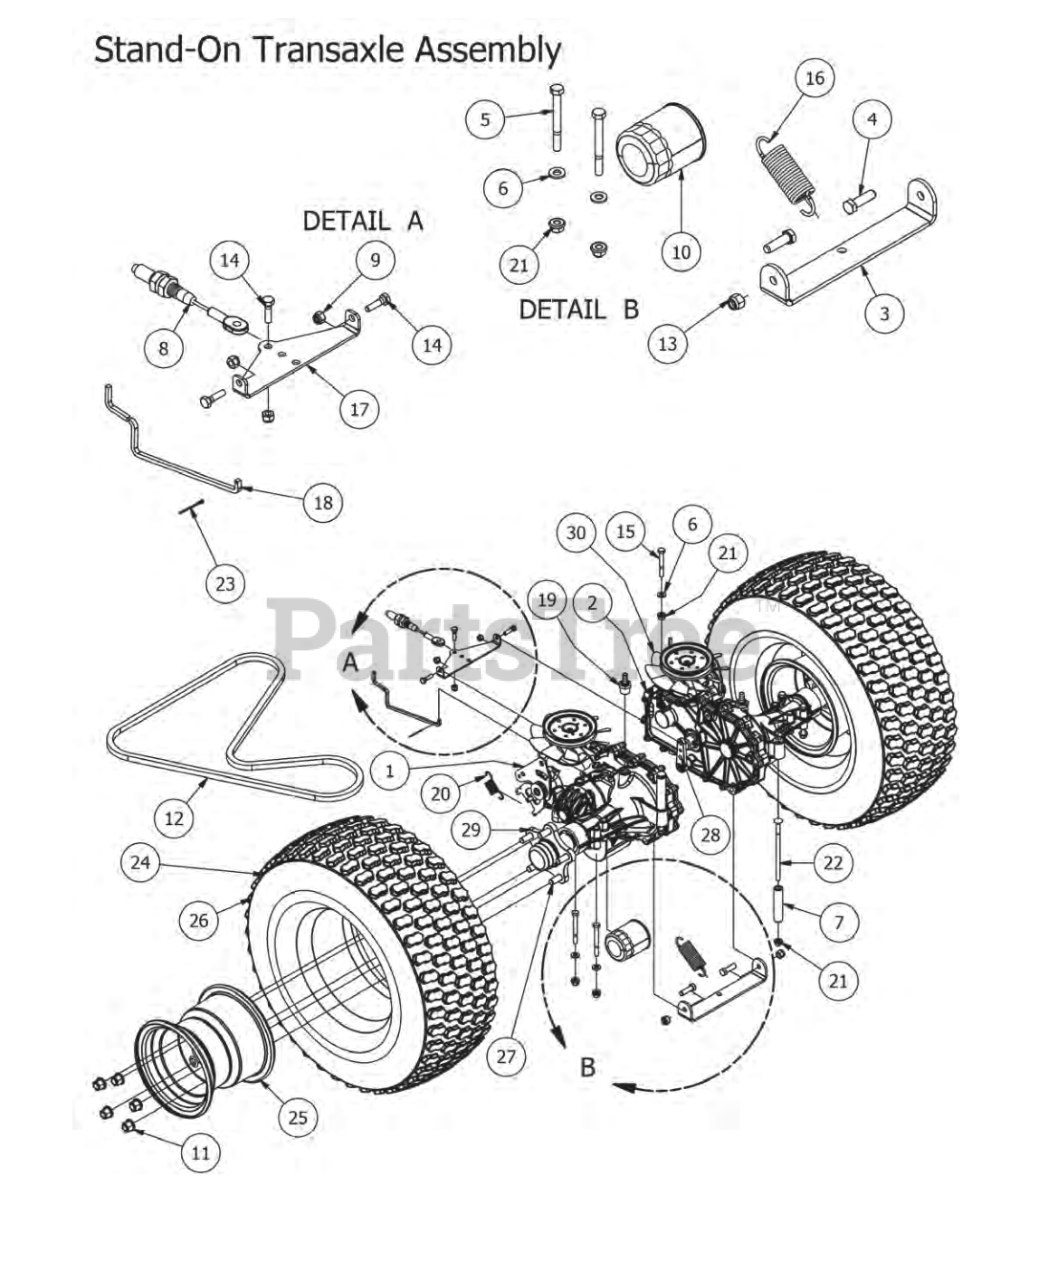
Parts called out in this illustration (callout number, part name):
1	Left 3400 IZT
2	Right 3400 IZT
3	Crossover Bar for ZT
4	3/8" x2" Hex Bolt
5	5/16" x 3" Hex Bolt
6	5/16" Flat Washer
7	3 1/4" Spacer
8	Brake Cable
9	1/4" Nylock Nut
10	Transaxle Hydro Filter
11	Acorn Lug Nut
13	3/8 Nylock Nut
14	1/4-20 x 1 GR 5 hex bolt zinc
15	5/16" x 2 1/2" Bolt
17	Brake Bracket
18	MZ Brake Release Bar
19	45 degree fitting
20	Spring for Stand On Models
21	5/16" Nylon Flange Nut
22	5/16" x 1 1/4" Carriage Bolt
23	Cotter Pin-Brake bar on Mz
24	23 x 10.50-12 Assembly W/Negative Offset Wheel
25	12 Orange Wheel
26	23 x 10.50-12 Tire
27	Transaxle Wheel Studs
28	Transaxle Brake Lever
29	Transaxle Hub
30	Fan/Pully Kit
